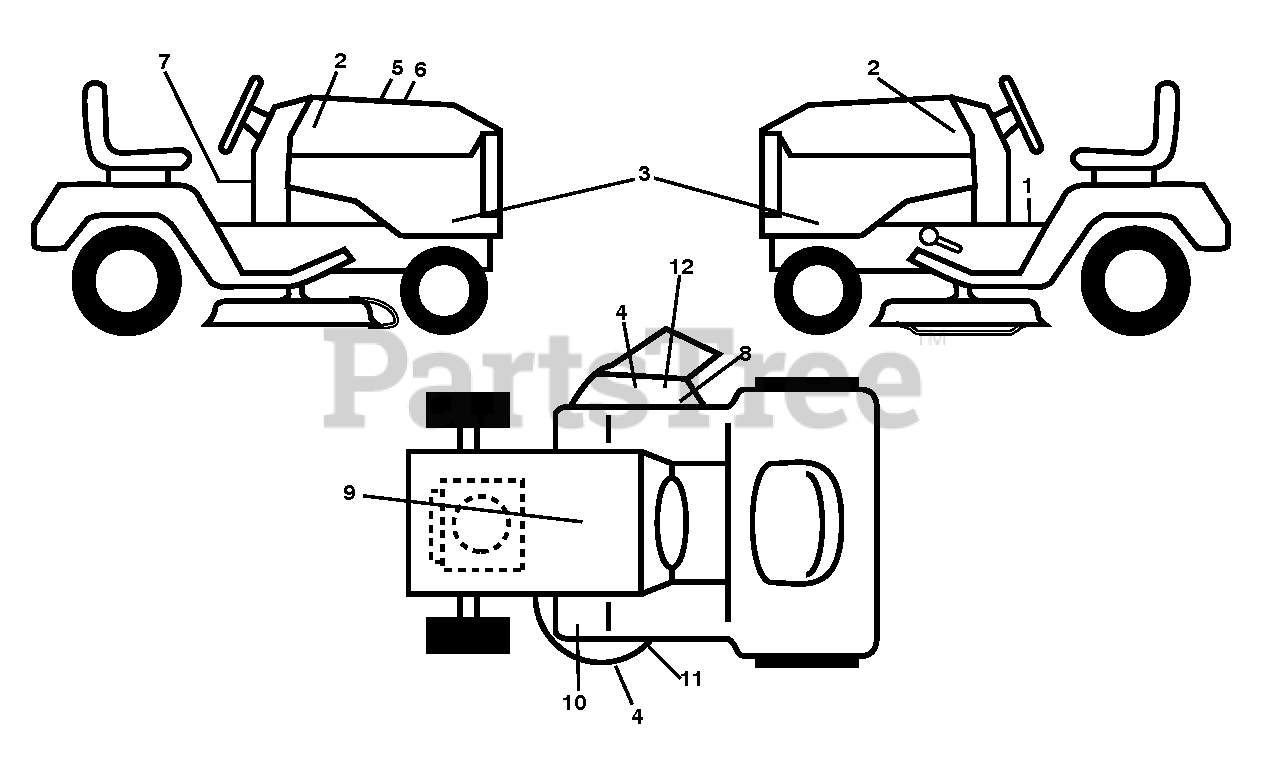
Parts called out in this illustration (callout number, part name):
1	DECAL.WARNING.2007.ENG/FR
2	DECAL.BADGE.170MM.TEXTLOGO.
3	DECAL.SDPNL.GT2.YT42XLS.SET
4	DECAL.DECK.6MIL.EURO.NOSTEP
5	DECAL.WARNING.CUST.RESP.E85.
7	DCL.WARNING.SPARK.IGNITION.CA
8	DECAL.DECK.6MIL./DEF.SHLD.WARN
9	DECAL BTRY SYMBOLS
10	DECAL.PEDAL.HUSQ.CROWN
11	DECAL.MOWER.SCH.48/54.PREM
12	DECAL, DECK DEFLECTOR, WARNING
